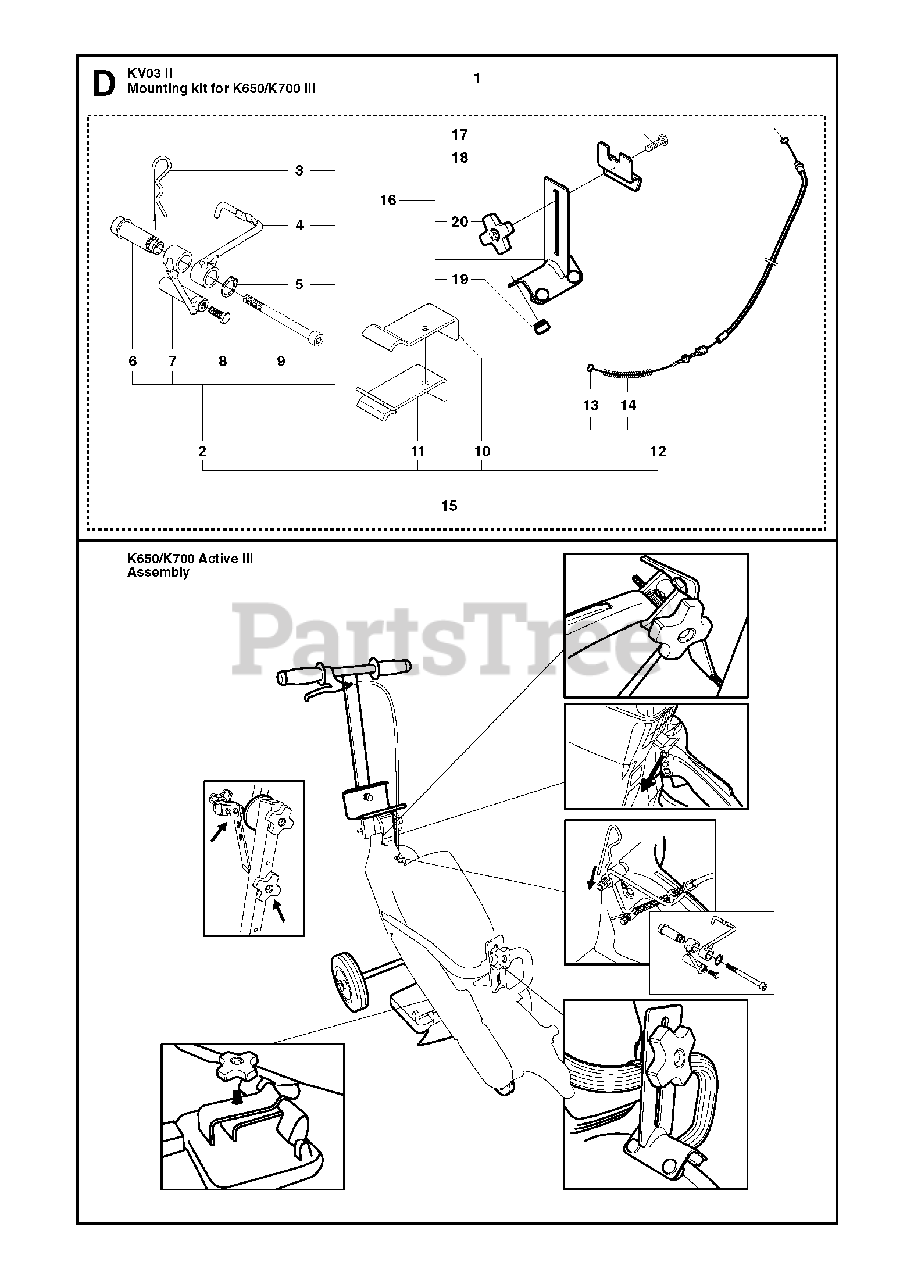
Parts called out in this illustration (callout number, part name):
1	ASSEMBLY KITIncl. 15, 16
2	KITIncl. 3 - 9
12	THROTTLE WIREIncl. 13, 14
15	KITIncl. 2, 10, 11, 12
16	RETAINERIncl. 17, 18, 19, 20
20	STEERING WHEEL
